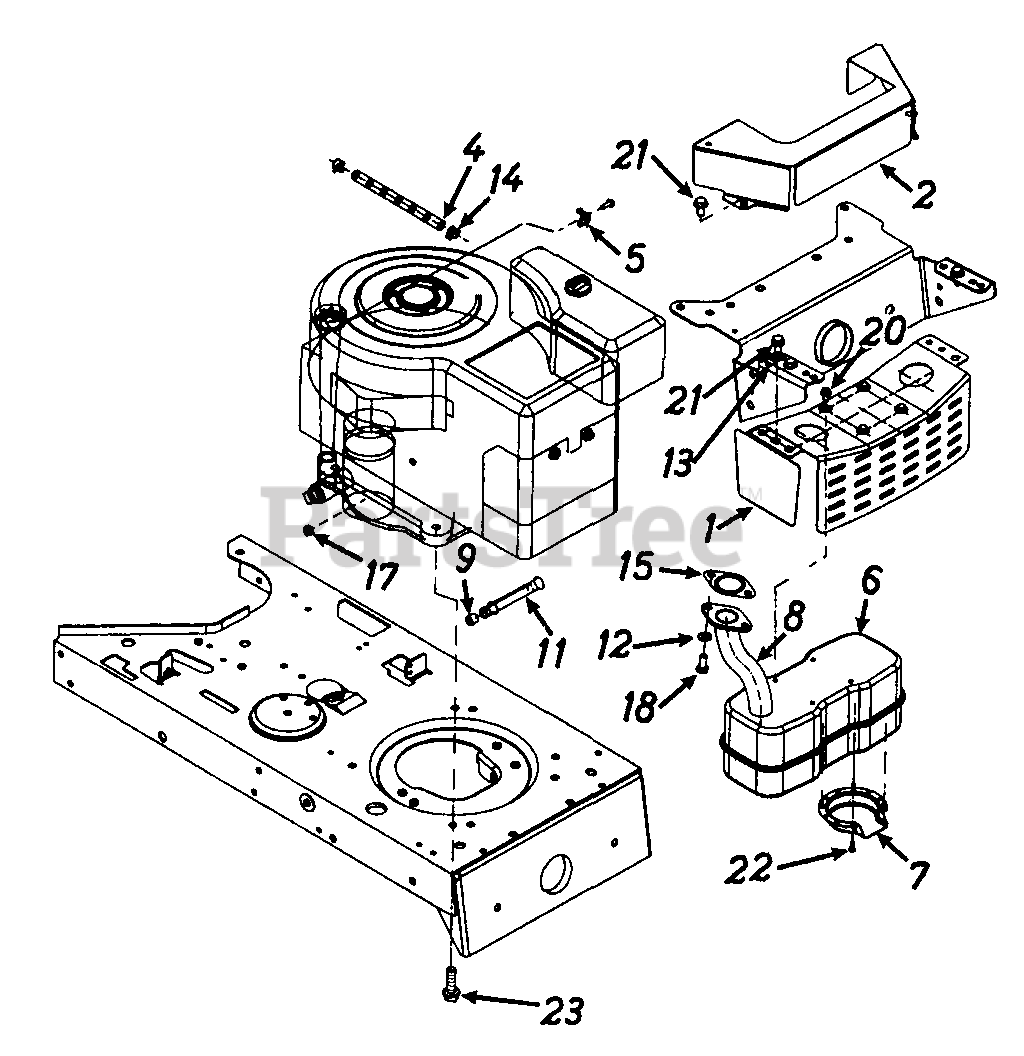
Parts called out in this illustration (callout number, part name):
1	Heat Shield Bracket
4	Fuel Line
5	Casing Clamp
6	Muffler
7	Muffler Deflector
8	Exhaust Pipe
9	Hex Pipe Plug
11	Pipe 3/8 NPT x 3.8" Lg.
12	L-Wash 5/16" I.D.
13	Clamp
14	Hose Clamp
15	Exhaust Gasket
17	Hex Sems Nut 1/4-20 Thd
18	Socket Hd Bolt 5/16-18 x .62" Lg.
20	Hex Wash. Hd. TT-Scr. 1/4-20 x .5" Lg.
21	Hex Wash. Hd. TT-Scr. 5/16-18 x .62" Lg.
22	Hex Bolt #8-32 x 38" Lg.
23	Hex Wash. Hd. TT-Scr 3/8-16 x 1.25" Lg.
